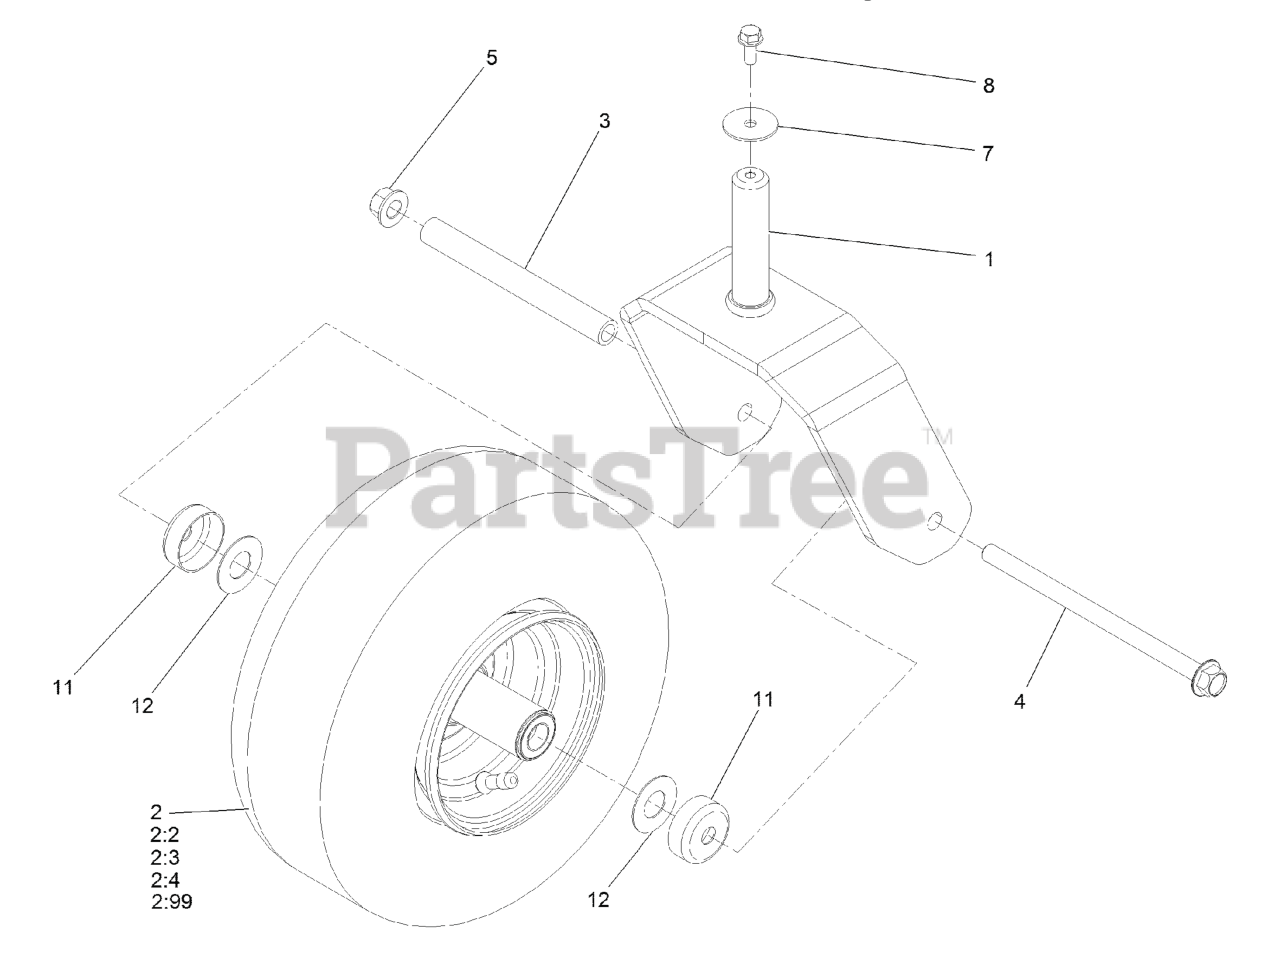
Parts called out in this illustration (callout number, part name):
2	TIRE AND WHEEL ASM
2:3	Stem-Valve
2:4	BEARING
3	SPANNER-WHEEL
4	SCREW-HHF
5	Nut-Lock 1/2-13
7	WASHER-FLAT
8	SCREW-HHF
11	GUARD-SEAL
